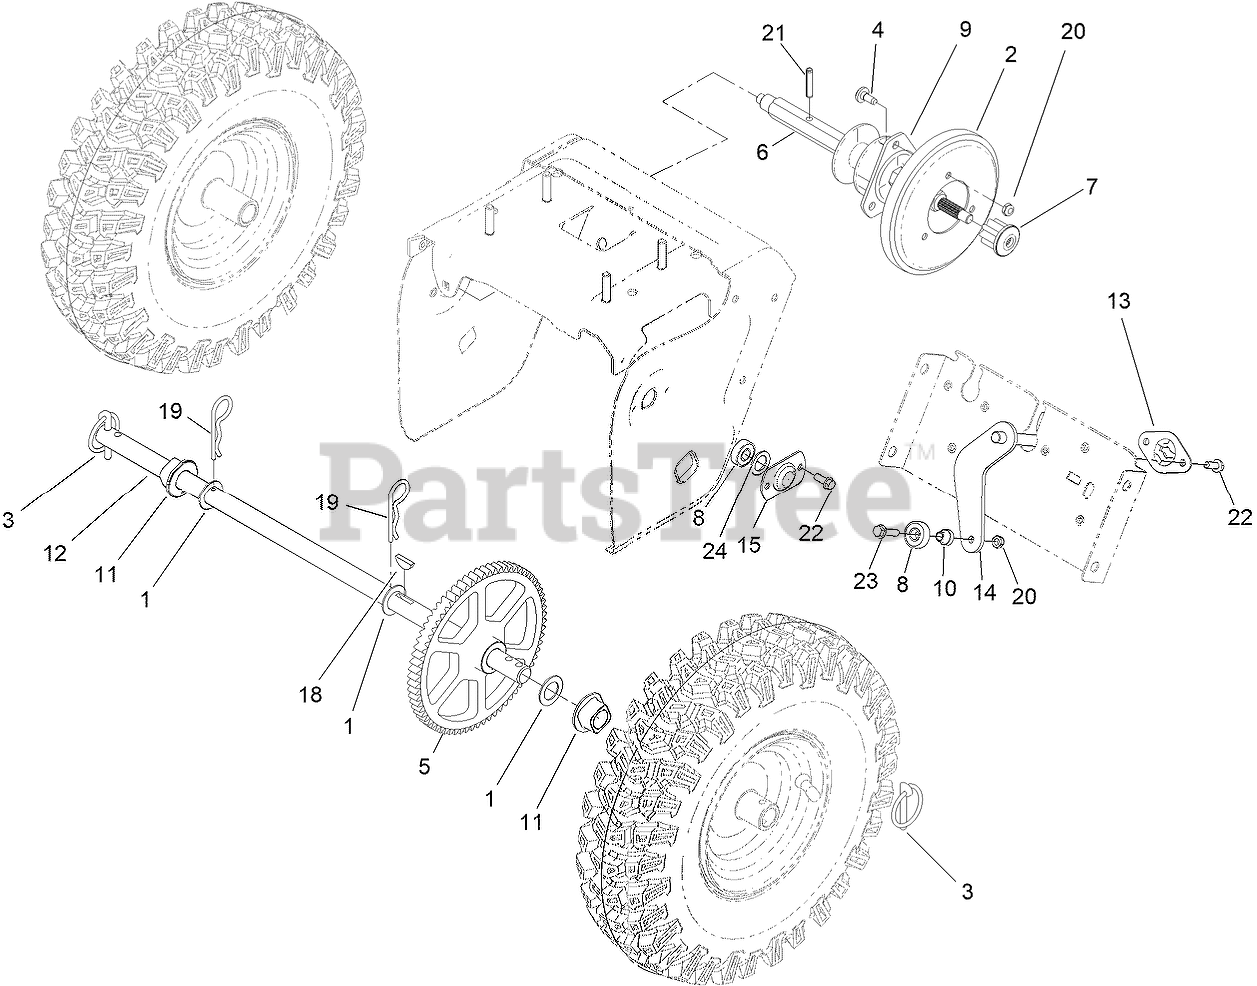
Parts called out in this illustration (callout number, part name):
1	WASHER-THRUST
2	WHEEL-FRICTION
3	KLIK PIN ASM
4	SCREW-SHOULDER
5	GEAR-AXLE
6	SHAFT-HEX
7	GEAR-PINION, 8 TOOTH
8	BEARING-BALL
9	TRUNNION
10	SPACER-PLATE, SHIFT
11	BUSHING-AXLE
13	RETAINER-PLATE, SHIFT
14	SHIFT PLATE ASM
15	RETAINER-BEARING
18	KEY-WOODRUFF
19	PIN-HAIR
20	NUT-HEX
21	PIN-ROLL, SLOTTED
22	SCREW-HWH
23	SCREW-HWHTF
24	WASHER-RUBBER
